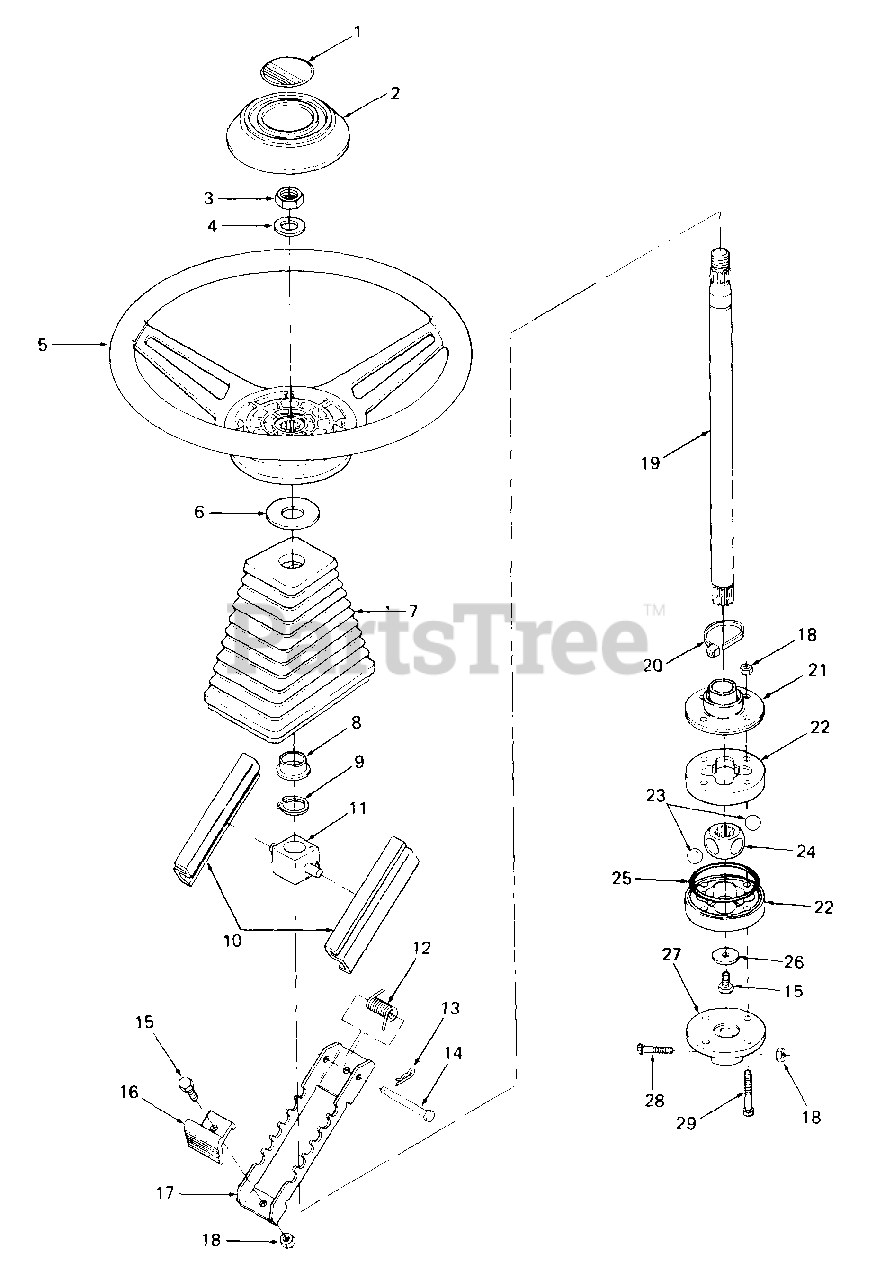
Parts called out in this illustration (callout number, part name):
1	Label, Steering Cap
2	Cap, Steering Wheel
3	Nut, Hex Jam, 5/8-18
4	Washer, Flat, .640 X 1.24 X .06 Thk HDN
5	Wheel, Steering
6	Washer, Flat, .758 X 2.0 X .030 Thk
7	Boot, Steering Shaft
8	Bearing, Flange
9	Ring, Snap
11	Bushing, Shaft Guide
12	Spring-Tilt, Torsion
13	Pin, Internal Cotter
14	Pin, Clevis, .25 Dia X 2.38 Lg
15	Screw, Hex Cap, 1/4-20 X .50 Lg GR5
16	Button, Tilt Control
17	Plate, Tilt Control
18	Nut, Hex Patch Lock, 1/4-20
19	Shaft, Upper Steering, 16.75 Lg
20	Strap, Tie
21	Boot, Coupling
22	Coupling, Drive w/O-Ring Groove
23	Ball, Steel, 5/8 Dia Chrome
24	Hub, Drive
25	O-Ring, 2.489 X .070
26	Washer, Flat, .265 X 1.0 X .030 Thk HDN
27	Adapter, Steering
28	Screw, Socket Hd Cap, 1/4-20 X 1.12 Lg
29	Screw, Socket Hd Cap, 1/4-20 X 1.75 Lg
